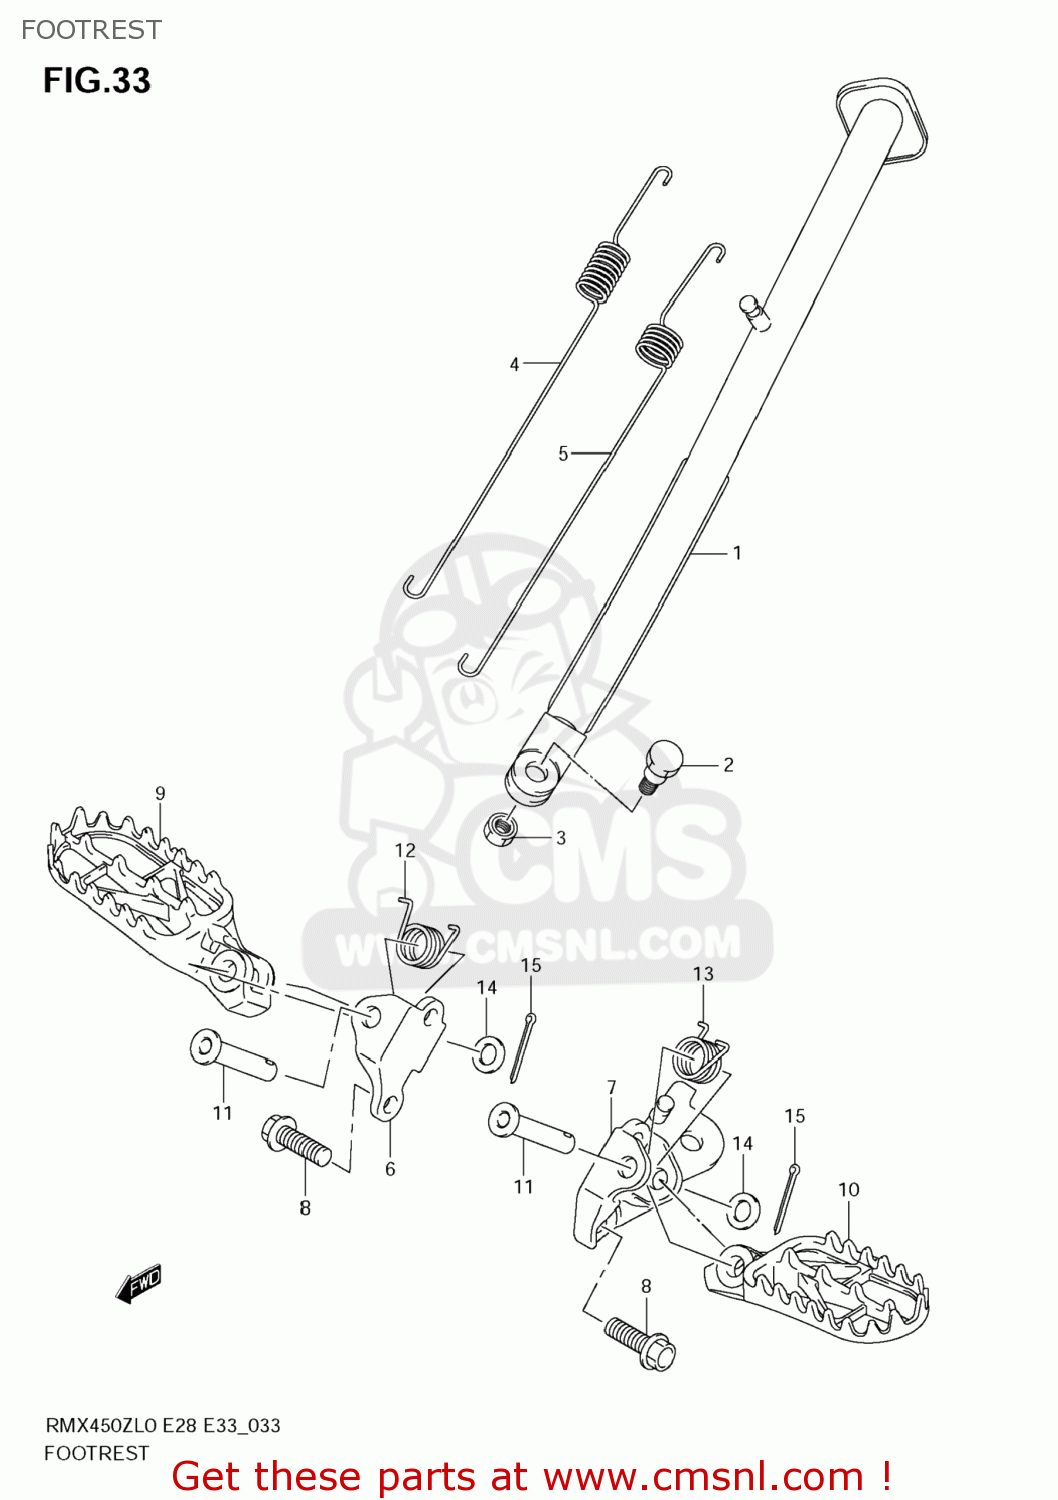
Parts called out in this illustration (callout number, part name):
1	STAND,PROP
2	BOLT(10X33)
3	NUT,PROP STAND
4	SPRING,PROP STAND
5	SPRING,PROP STAND OUTER
6	BRACKET,FOOTREST,R
7	BRACKET,FOOTREST,L
8	BOLT(10X25)
9	FOOTREST,R
10	FOOTREST,L
11	PIN(10X41.5)
12	SPRING
13	SPRING
14	WASHER(10.5X18X1)
15	PIN
